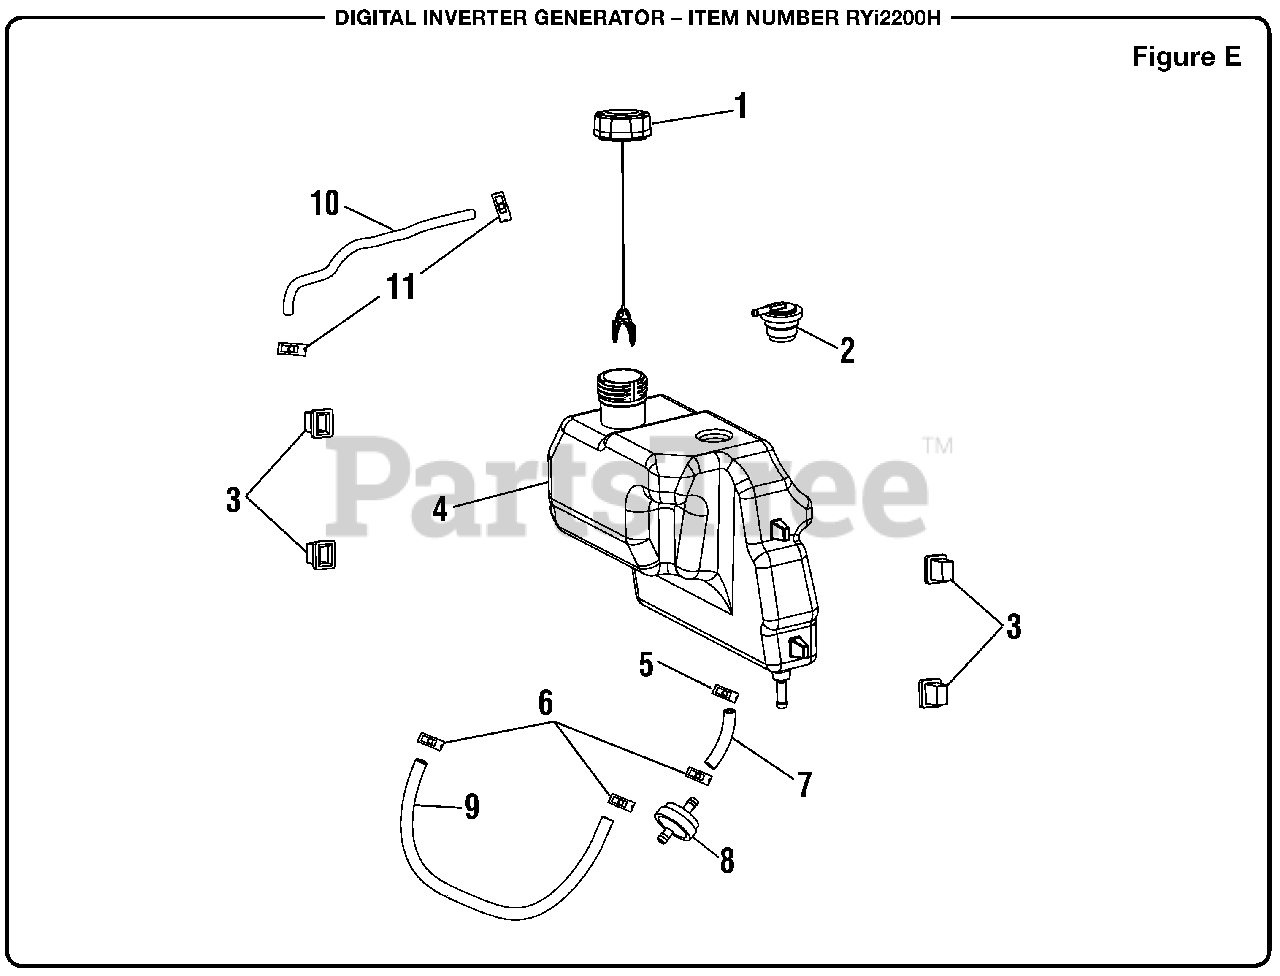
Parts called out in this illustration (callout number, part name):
2	Vapor Vent
3	Fuel Tank Support
4	Fuel Tank
5	Hose Clamp (10 mm)
6	Hose Clamp (95 mm)
7	Fuel Hose (Fuel Tank To Fuel Filter)
8	Inline Fuel Filter (1/4 in)
9	Fuel Hose (Fuel Filter To Fuel Pump)
10	Air Hose (Fuel Tank To Carbon Canister)
11	Clamp (M85)
